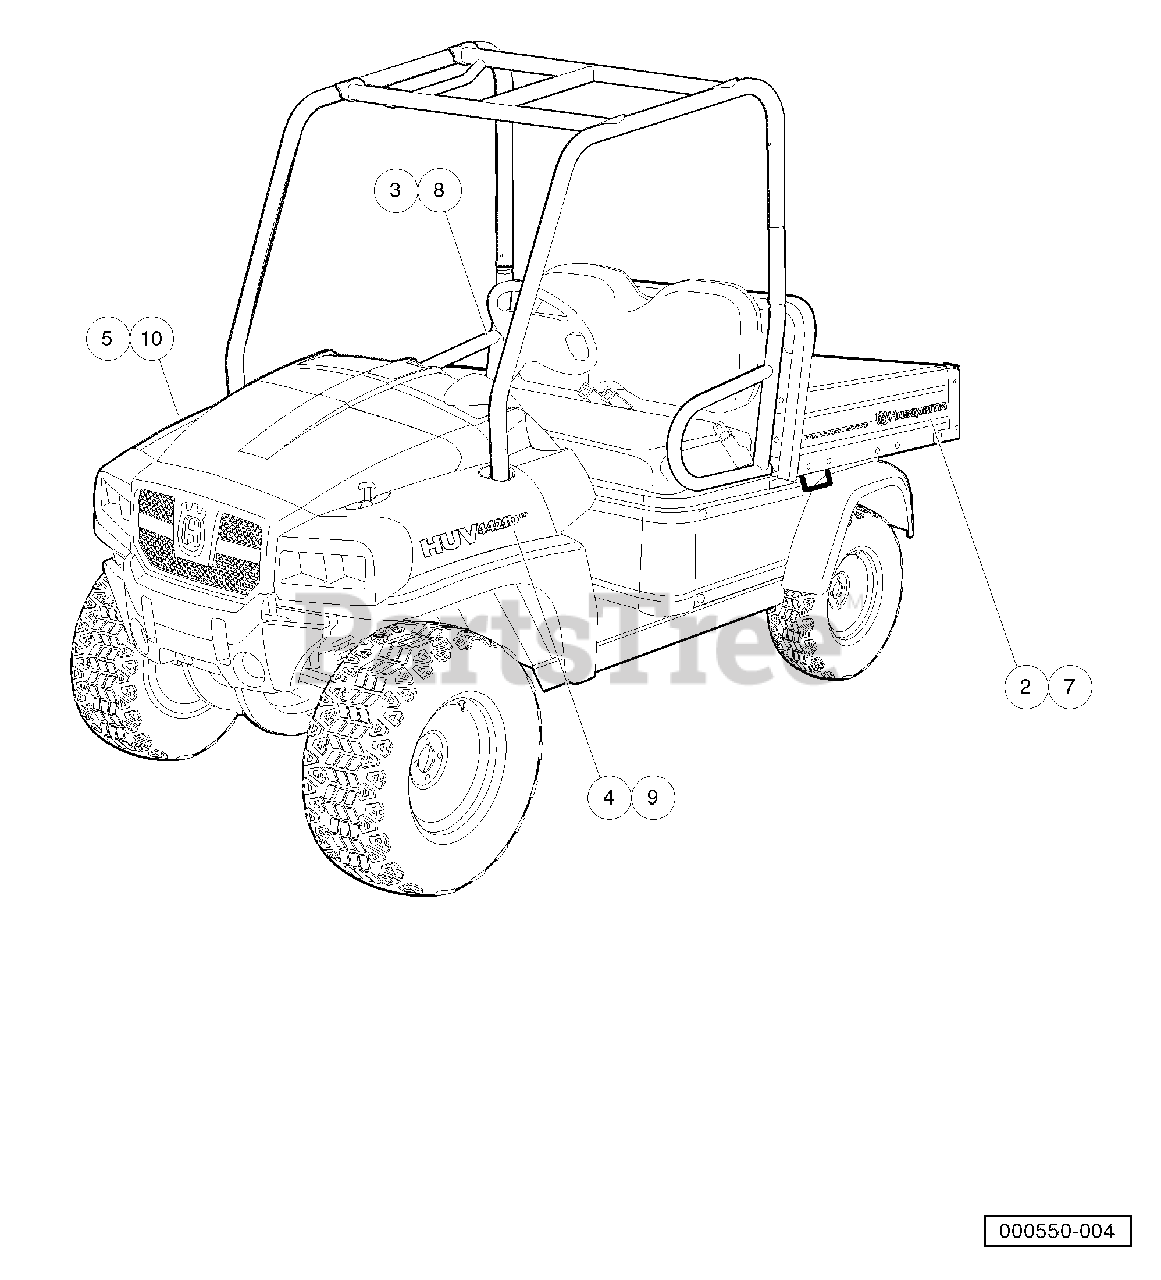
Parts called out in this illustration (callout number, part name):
2	Decal, Bed, Huv, Orange, Ds
3	Decal, Bed, Huv, Orange, Ps
4	Decal,huv 4421dxp, Orange, Ds
5	Decal,huv 4421dxp, Orange, Ps
6	Instl,decal,huv4421dxp,olv Grn
7	Decal, Bed, Huv, Olv Grn, Ds
8	Decal, Bed, Huv, Olv Grn, Ps
9	Decal,huv 4421dxp, Olv Grn, Ds
10	Decal,huv 4421dxp, Olv Grn, Ps
